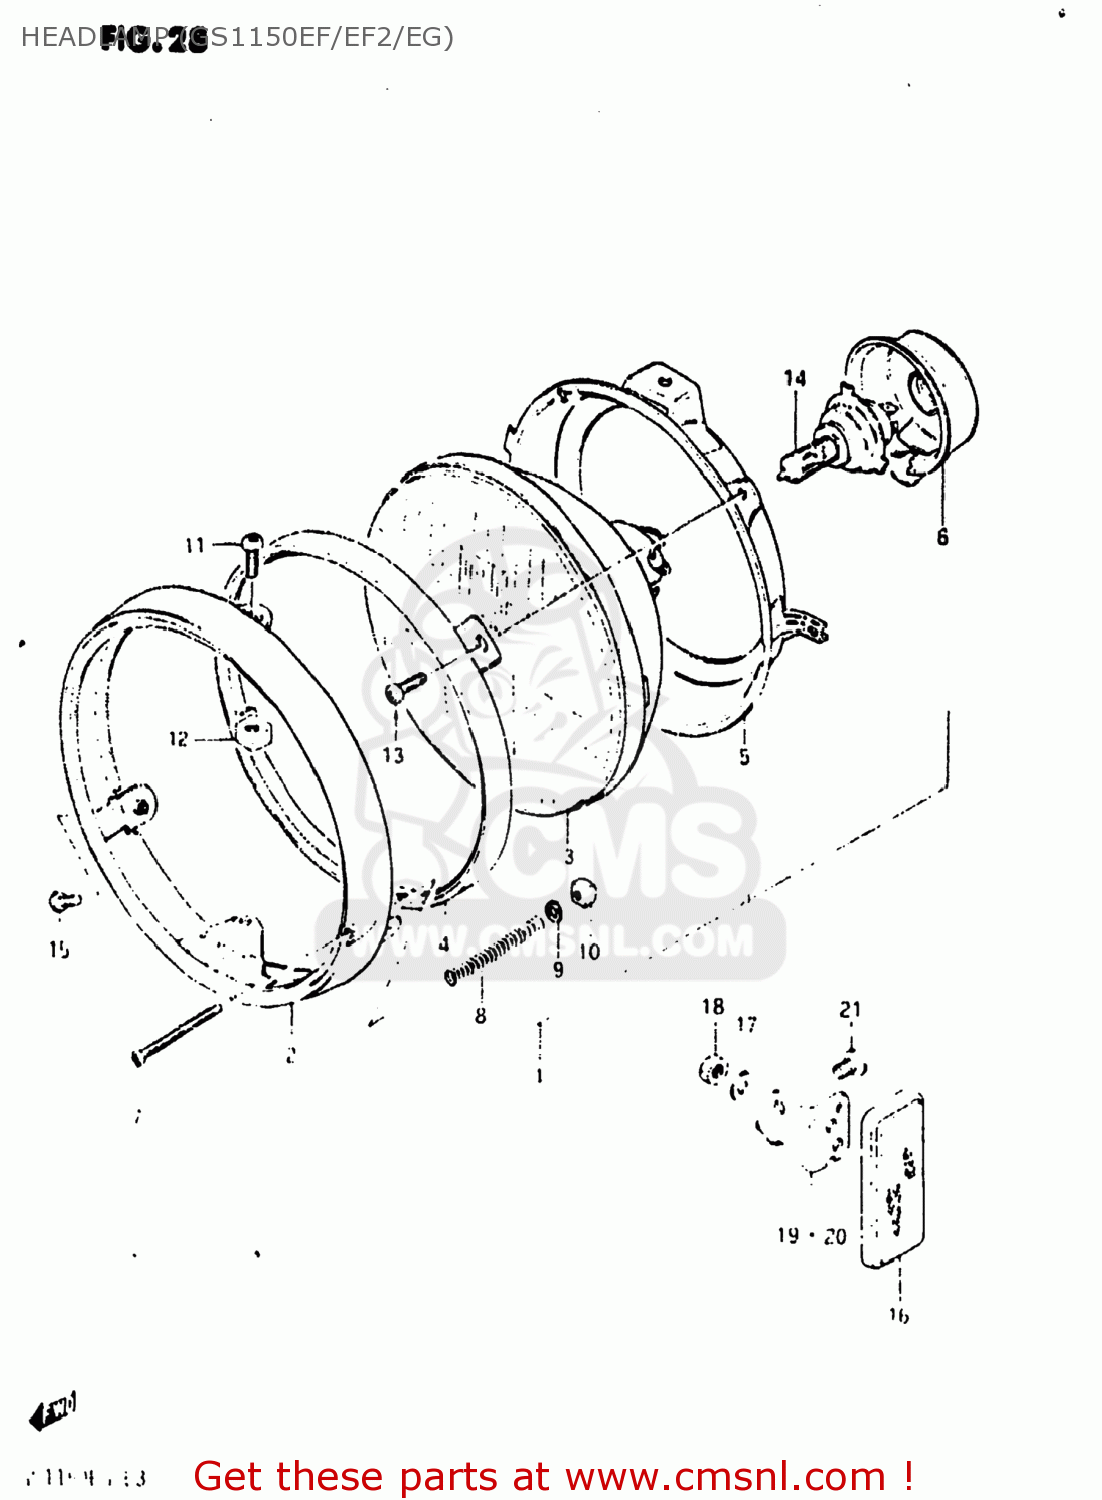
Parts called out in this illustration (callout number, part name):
1	LAMP ASSEMBLY,HEAD
2	RIM,HEADLAMP
3	LAMP UNIT
4	RETAINER
5	RING,MOUNTING
6	COVER,HEADLAMP SOCKET
7	SCREW
8	SPRING,HEADLAMP ADJUST
9	WASHER
10	NUT
11	SCREW
12	NUT
13	SCREW
14	BULB(12V60/55W,H4)
15	SCREW
16	REFLEX REFLECTOR,FR SIDE
17	WASHER,5MM
18	NUT ,5MM
19	BRACKET,FRONT SIDE REFLECTOR
20	BRACKET,FRONT SIDE REFLECTOR
21	SCREW
